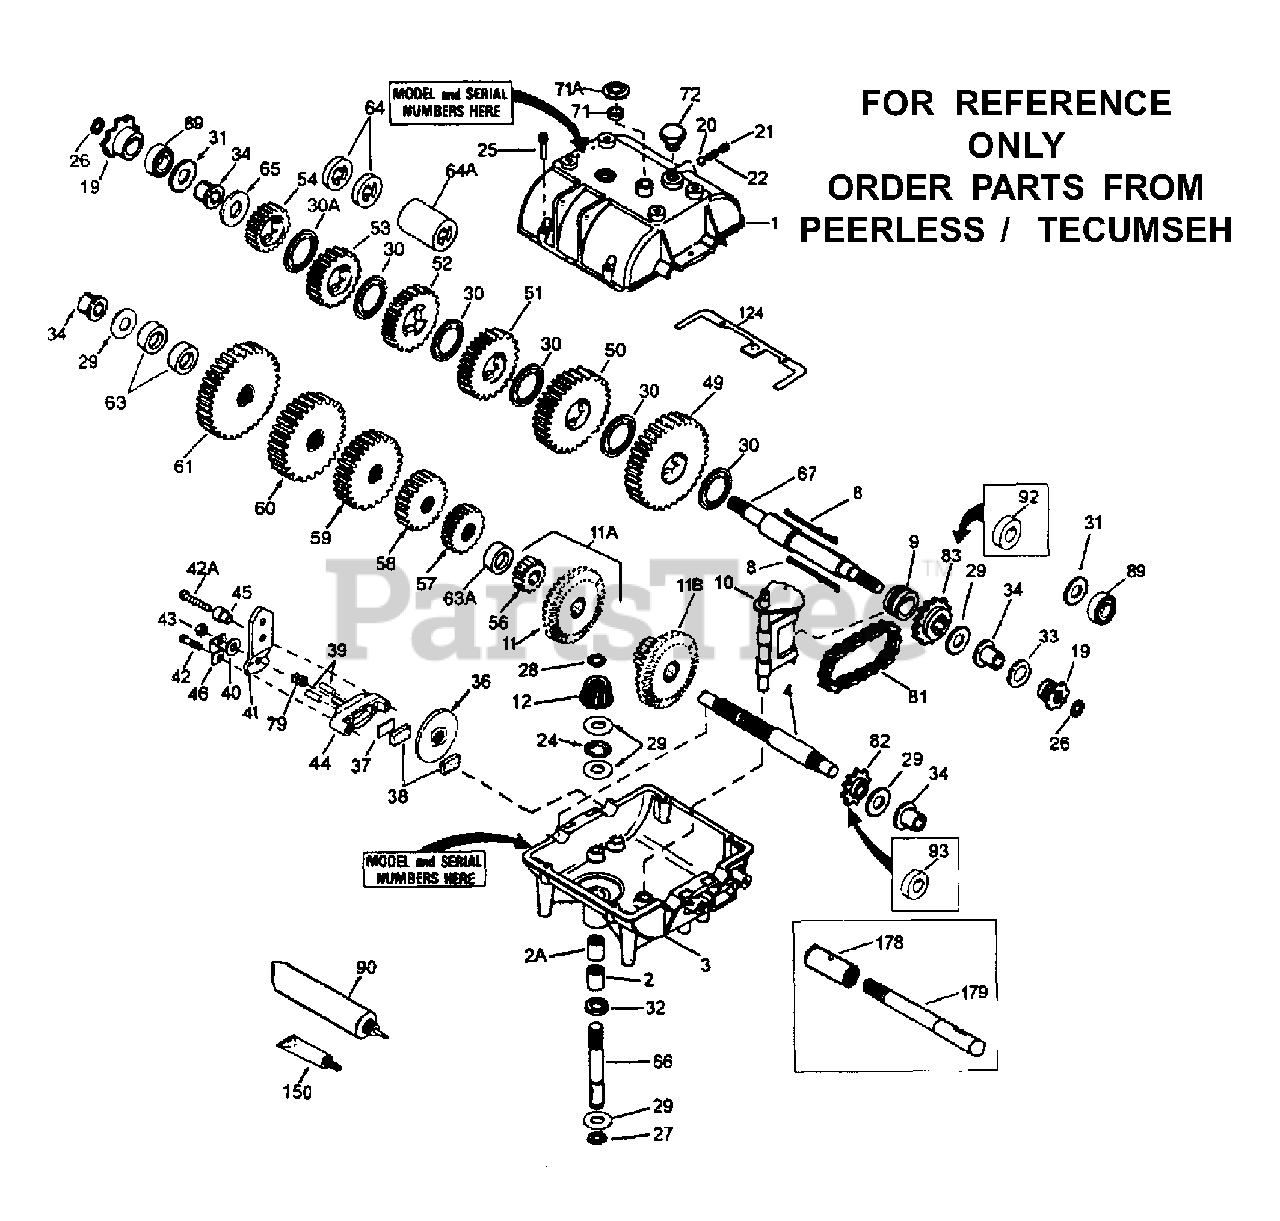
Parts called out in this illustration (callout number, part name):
1	Case, Transmisson
2	Needle Bearing Grease Spec
2A	Needle Bearing
3	Case, Transmission
8	Shift Key
9	Shift Collar
10	Shift Rod & Fork
11	Bevel Gear (42 teeth)
12	Bevel Pinion (14 teeth-steel)
20	Steel Ball, 5/16" dia.
21	Set Screw, 3/8-16 x 3/8"
22	Spring
24	Thrust Bearing
25	Screw, 1/4-20 x 1-1/4" (6)
27	Retaining Ring
28	Retaining Ring
29	Washer (6)
30	Washer (5)
32	"O" Ring
34	Flanged Bushing
49	Spur Gear (37 teeth)
50	Spur Rear (35 teeth)
51	Spur Gear (32 teeth-steel)
52	Spur Gear (30 teeth)
53	Spur Gear (25 teeth)
56	Spur Gear (12 teeth-steel)
57	Spur Gear (15 teeth)
58	Spur Gear (18 teeth-steel)
59	Spur Gear (20 teeth)
60	Spur Gear (25 teeth)
65	Washer
66	Input Shaft (3-11/16" long)
67	Shifter & Brake Shaft
71	Square Cut Ring
72	Threaded Plug
81	Roller Chain (No. 41 chain, 24 links)
82	Sprocket (9 teeth)
83	Sprocket (18 teeth)
90	Grease (32 oz. bottle Bentonite grease)
150	Gasket Eliminator (Loctite #515)
178	Coupling
179	Connector Shaft
